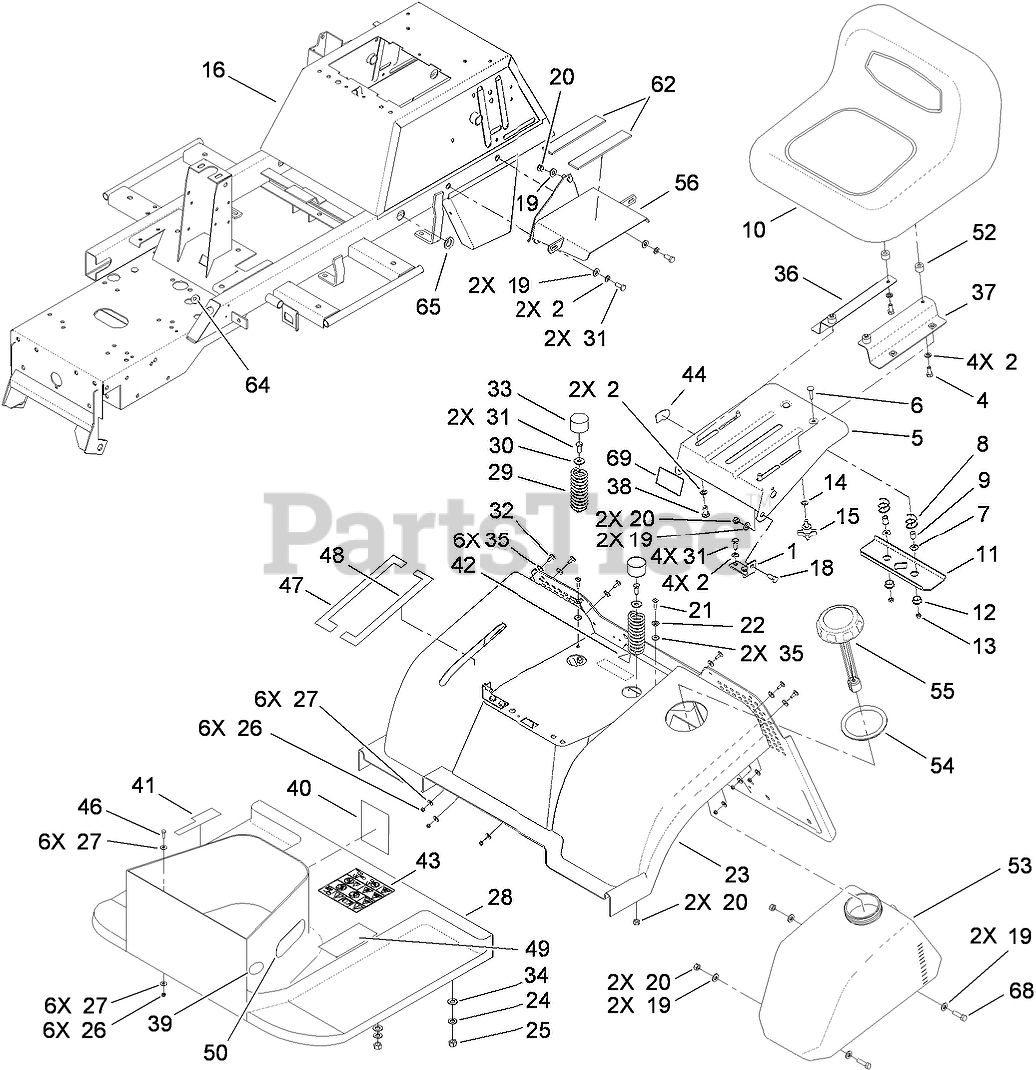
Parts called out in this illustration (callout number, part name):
1	BRACKET-SUPPORT, SEAT
2	WASHER-LOCK
4	SCREW-HH
5	SUPPORT-SEAT
6	BOLT-CARRIAGE
7	WASHER-FLAT
8	SPRING-SEAT
9	SPACER-SPLIT
10	SEAT ASM
11	BRACKET
12	BUSHING
13	NUT-LOCK
14	WASHER-SPRING
15	KNOB-ADJUSTMENT
16	CHASSIS-FRAME
18	SCREW-SUPPORT, SEAT
19	WASHER-PLAIN
20	NUT-LOCK, NI
21	SCREW-HSFH
22	WASHER-FINISH
23	FENDER-BODY, REAR
24	WASHER-FLAT
25	NUT-LOCK, NI
26	NUT-LOCK
27	WASHER-FLAT
28	FOOTREST ASM
29	SPRING-SEAT
30	WASHER-PLAIN
31	SCREW-HH
32	BOLT-CARRIAGE
33	CAP-HUB
34	WASHER-RUBBER
35	WASHER-RUBBER
36	BRACKET-SEAT, RH
37	BRACKET-SEAT, LH
38	Screw
39	DECAL-BRAKE, PARKING
40	DECAL-STARTING
41	DECAL-OPERATION, HYDRO
42	DECAL-BAG TO FRAME
43	DECAL-DANGER
44	DECAL-SWITCH
46	SCREW-HH
47	DECAL-HOC, LH
48	DECAL-HOC, RH
49	DECAL-OPERATION
50	DECAL-TOWER
52	SHIM-SEAT
53	TANK-FUEL
54	PROTECTOR-NECK, FILLER
55	CAP-FUEL
56	BRACKET-FUEL, TANK
62	STRIP-RUBBER, FUEL TANK
64	GROMMET
65	GROMMET
68	SCREW-HH
69	DECAL-DANGER
